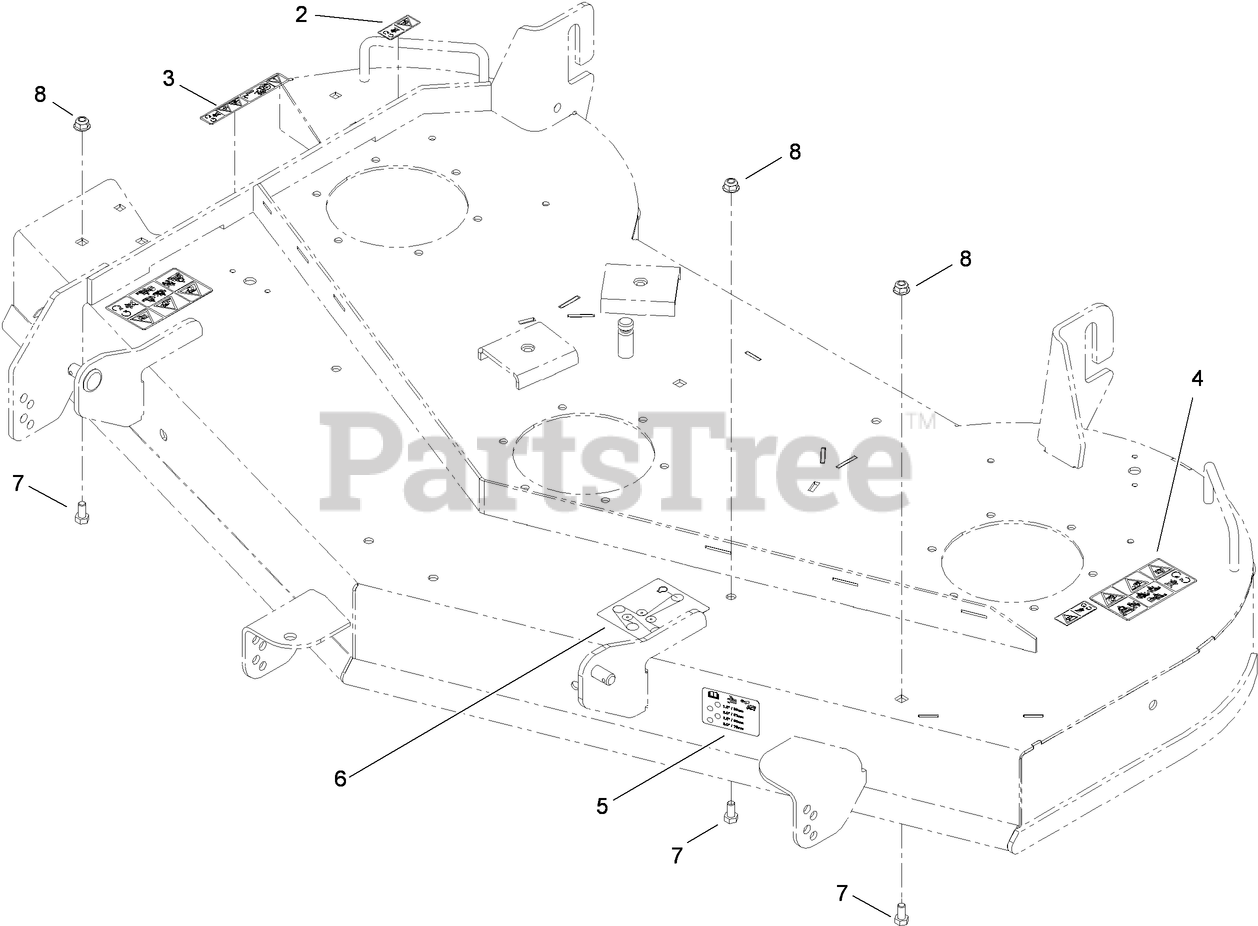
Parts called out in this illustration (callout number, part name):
2	DECAL-DANGER
3	DECAL-DANGER
4	DECAL-DANGER
5	DECAL-SCALP, ANTI
6	DECAL-ROUTING, BELT
7	SCREW-HH
8	NUT-HF, NI
